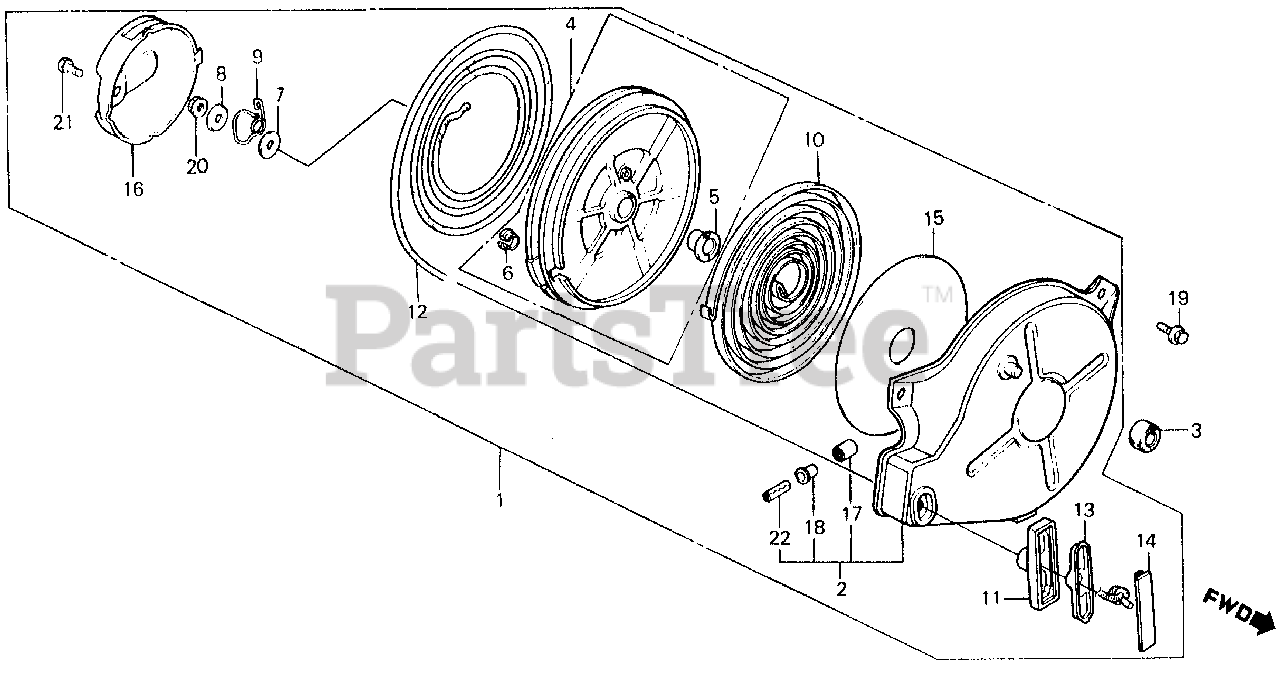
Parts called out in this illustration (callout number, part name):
1	STARTER ASSY., RECOIL (NOT AVAILABLE)
2	CASE, STARTER
3	RUBBER, STOPPER (NOT AVAILABLE)
4	REEL, STARTER
5	BOSS, REEL (NOT AVAILABLE)
6	BUSH, REEL STARTER
7	PLATE A, FRICTION (NOT AVAILABLE)
8	PLATE B, FRICTION (NOT AVAILABLE)
9	SPRING, FRICTION
10	SPRING, RETURN (NOT AVAILABLE)
11	GRIP, STARTER (NOT AVAILABLE)
12	ROPE (#4X91")
13	SUPPORT, GRIP
14	COVER, GRIP
15	PLATE, SIDE (NOT AVAILABLE)
16	COVER, STARTER REEL
17	ROLLER, GUIDE
18	BUSH, ROLLER
19	BOLT, FLANGE (5X10)
20	NUT, SELF-LOCK (6MM)
21	BOLT, HEX. (5X10)
22	PIN, SPRING (3X18)
